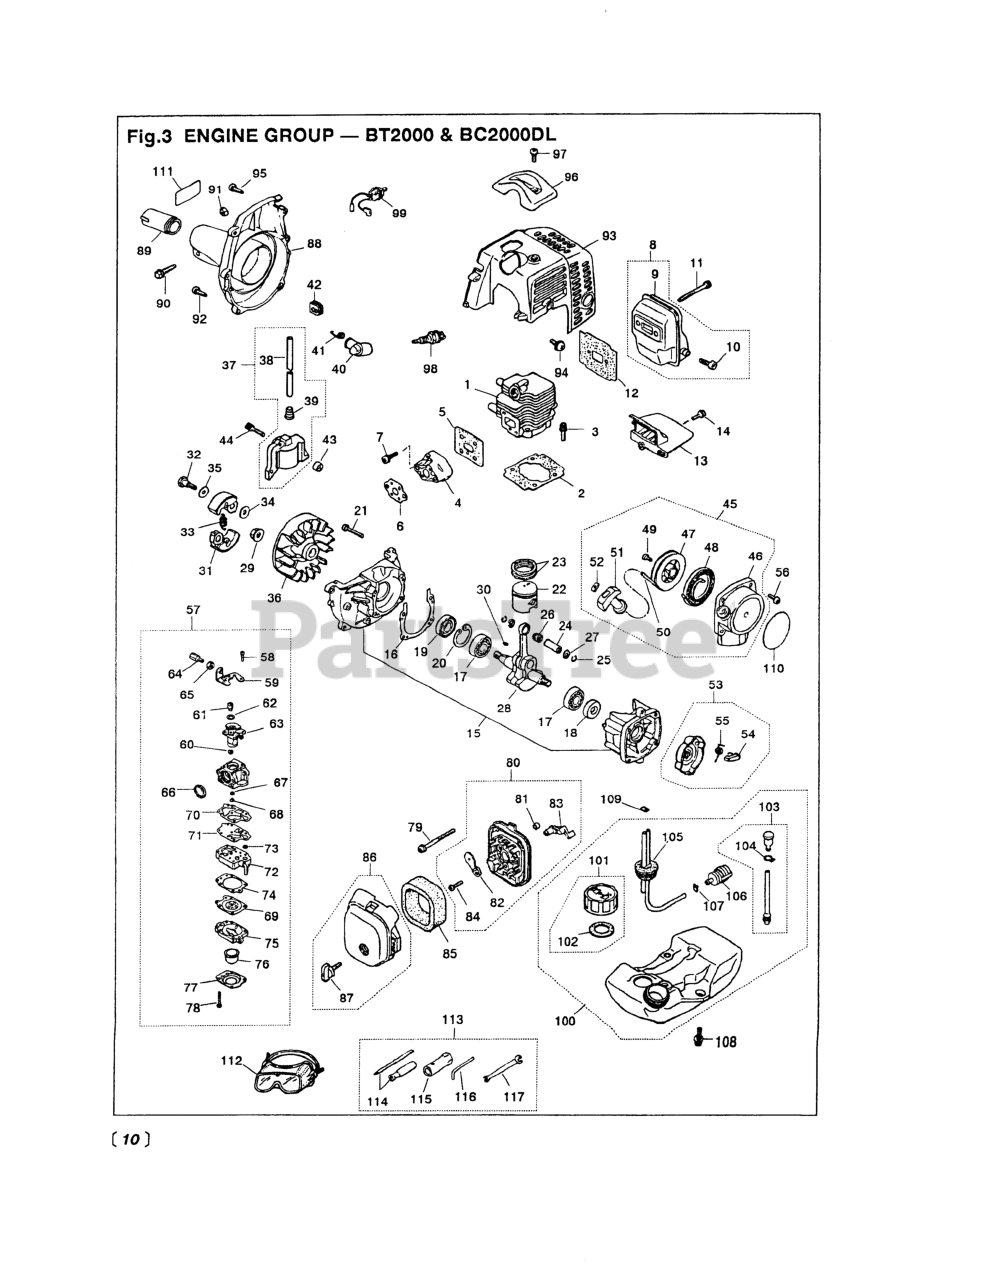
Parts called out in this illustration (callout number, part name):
1	CYLINDER
3	BOLT, M5 X 22
7	SCREW, M5X20 (RPLS.1400-75510)
9	MUFFLER ASSY (USE 5913-15100)
10	ARRESTER (RPLS 5850-15140)
11	BOLT, M5 x 50
12	GASKET, MUFFLER
14	SCREW, M4 X 16
15	CRANKCASE
17	BEARING
18	SEAL, OIL (RPLS 1100-21210)
19	SEAL, OIL (RPLS 1140-21220)
20	RING, SNAP, M28 x 1.2
21	SCREW, M5 x 30(RPLS 0263-00530
24	PIN, PISTON 5x8x26
25	RING, SNAP (RPLS 1101-41320)
27	WASHER
30	KEY
32	BOLT
34	WASHER, FLAT (USE 182303)
38	CORD
39	CAP
41	SPRING
42	GROMMET
44	BOLT
45	RECOIL ASSEMBLY
46	CASE
47	REEL
48	SPRING, SPIRAL
49	SCREW (RPLS -75150)
51	KNOB
52	PLATE, STOPPER
53	PULLEY ASSY (RPLS -75210)
54	RATCHET (RPLS 1850-75220)
55	SPRING, RETURN
56	SCREW, M4 X 16
58	SCREW
60	RING
61	SWIVEL
62	WASHER
63	VALVE ASSY (USE -81151)
64	SCREW, CABLE ADJUSTER
65	NUT, CABLE ADJUSTER
66	RING, PACKING
67	RING, O
69	DIAPHRAGM (USE 4810-81260)
70	GASKET, PUMP
71	DIAPHRAGM
72	BODY, PUMP
74	GASKET, DIAPHRAGM
75	BODY, PURGE
76	PUMP, PRIMING
77	COVER, PUMP
78	SCREW
79	SCREW, M5 X 55
81	SLEEVE
83	LEVER, CHOKE
84	SCREW (REPLACES 50030272)
85	ELEMENT
88	HOUSING COMPLETE
90	BOLT, M6x35 (RPLS -50635)
91	NUT, M6 X 5
92	SCREW, M5X20 (RPLS.1400-75510)
94	SCREW, M5 x 12
95	SCREW, HOUSING
96	GUARD, PLUG
97	SCREW, M5 X 12
99	SWITCH
102	PACKING
104	CLIP
105	PIPE COMPLETE
106	FILTER ASSY
107	CLIP (REPLACES 2841-31280)
108	SCREW
109	CLIP
111	LABEL, FAN COVER
113	TOOL SET
114	SCREWDRIVER
115	SOCKET, HEX, 3/4
116	BAR
117	SPANNER, 8 X 10 (RPLS 2540- )
